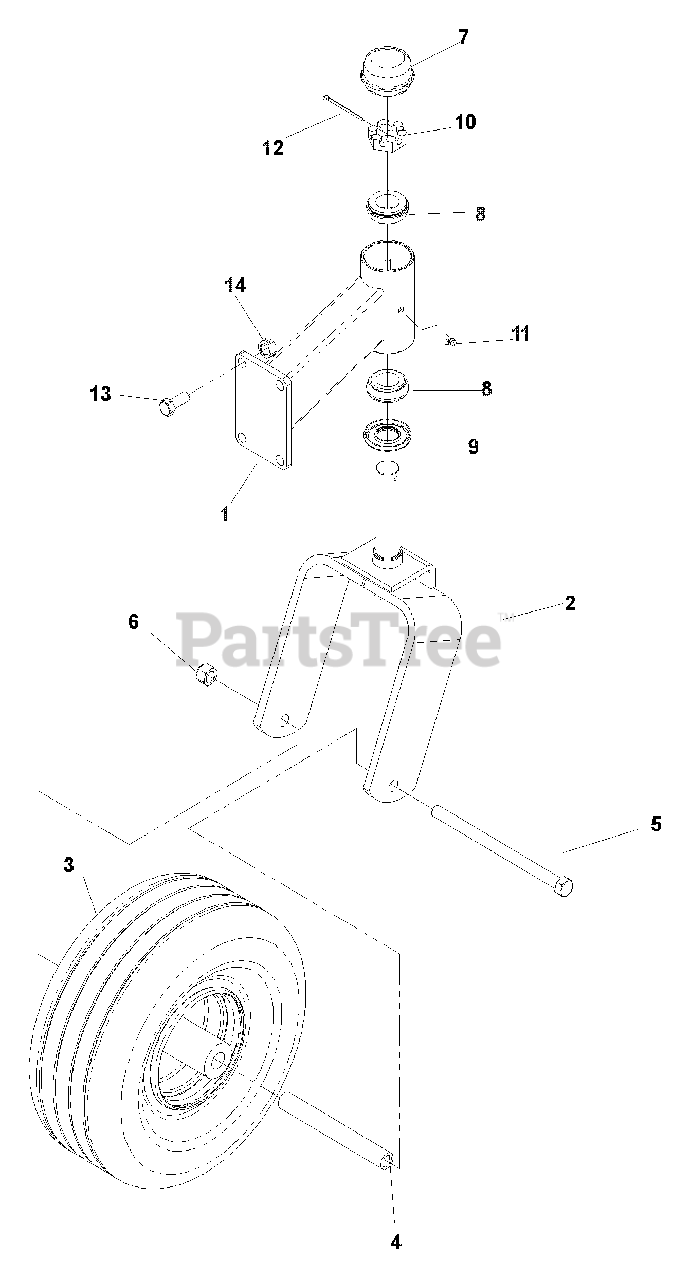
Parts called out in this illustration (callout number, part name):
1	CASTER ARM 61" DECK
2	CASTER YOKE
3	TIRE & WHEEL ASSEMBLY
3	TIRE
3	RIM
3	VALVE STEM
3	FLANGE BEARING
5	HCS 1/2-13 X 7 1/2
6	NUT 1/2C, NYLOC
7	GREASE CAP
10	NUT, 1"-14, SLOTTED JAM
12	PIN, COTTER, 1/8 X 2
13	HCS 7/16C X 1
14	NUT, 7/16C, LOCK
